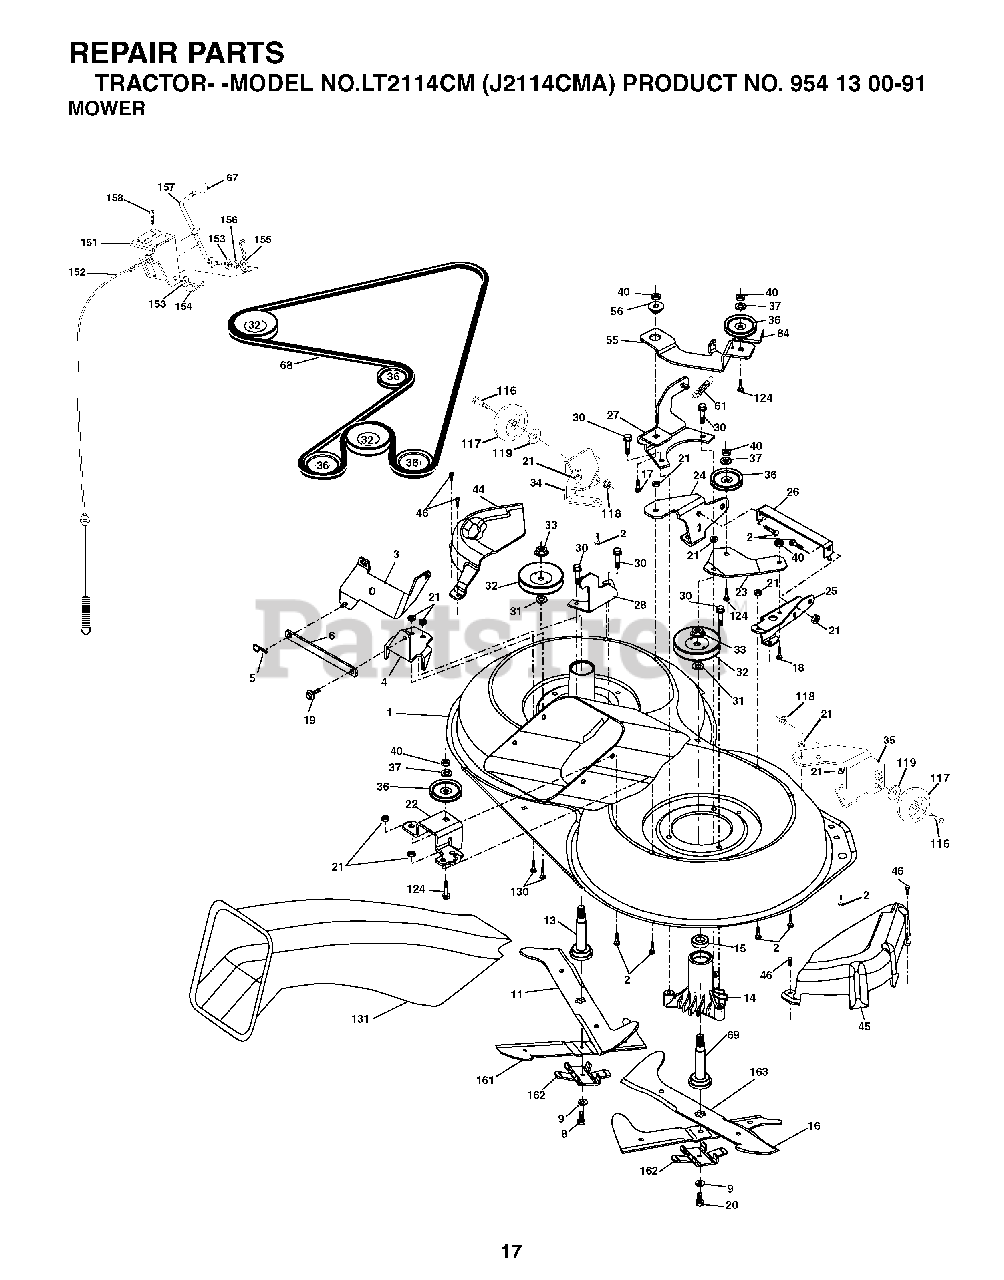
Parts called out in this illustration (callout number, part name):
1	MOWER HOUSING, DECK
2	BOLT
3	BRACKET
5	RETAINER-SPRNG RB
6	BAR SWAY
9	LOCKWASHER
11	BLADE-LH 5PT STAR(CTH130)
13	SHAFT ASM VENT
14	HSG MANDREL
16	BLADE RH 6PT STAR(CTH130)
17	BOLT.3/8-14X1.25
19	BOLT SHD 5/16-18
21	LOCKNUT
24	BRACKET
25	BRACKET
26	BRACE
28	BRACKET
30	SCREW, WASHER HEAD
31	WASHER
32	PULLEY, MANDREL
33	NUT, FLG TOPLOCK 9/16"
36	PULLEY.IDLER.4.25
40	LOCKNUT
45	MANDREL COVER
46	SCREW.1/4-20X5/8
55	ARM IDLER
56	SPACER.RETAINER.MOWER
61	SPRING.TENSION.BELT
67	KNOB T (3/8 HOLE)
68	HEX-BELT
69	SHAFT.ASM.W/LWR.BRG.RH.THREAD
84	KEEPER, BELT IDLER
116	SHOULDER BOLT
117	WHEEL GAGE DONUT
118	LOCKNUT
119	WASHER
124	BOLT.3/8-16X1.50
131	CHUTE BAGGER
151	BRACKET, CLUTCH CABLE
153	WASHER FLAT 3/8"
154	SPRING RETAINER
155	SPRING RETENTION LEVER
156	SPACER CLUTCH CABLE
157	ROD CLUTCH CABLE 3/8"
158	SCREW
